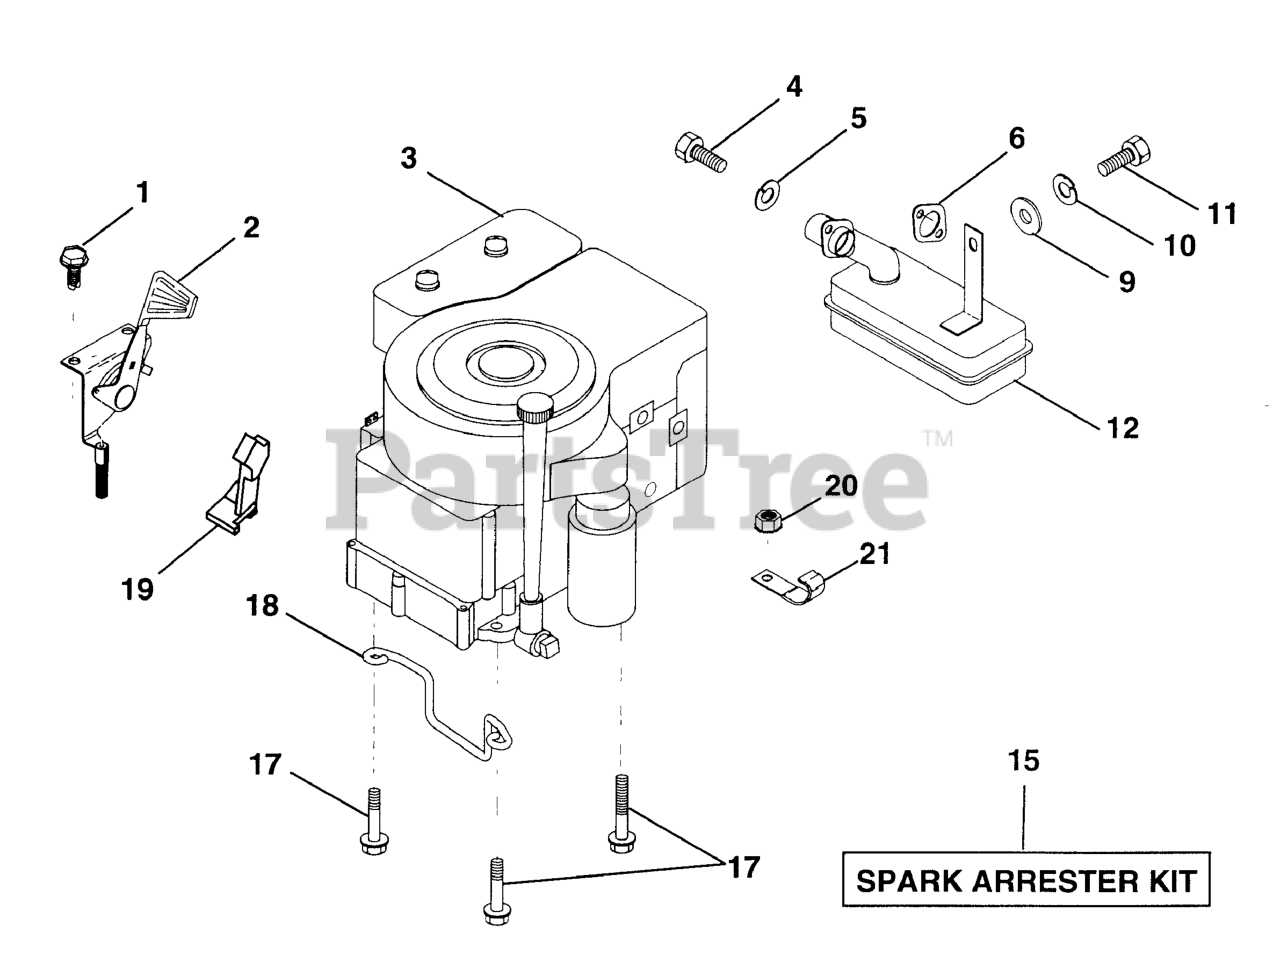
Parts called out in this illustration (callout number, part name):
2	CONTROL.TH/CH.RH.BLK.FLG.EEC
3	Engine, Briggs and Stratton Model No. 282707
4	SCREW
5	WASHER.LOCK.HVY.HLCL.SPR.5/16
6	GASKET ENGINE
9	WASHER
10	LOCKWASHER
11	Bolt, Hex Fin.
12	MUFFLER.SINGLE.B&S.12HP
15	KIT.SPARK ARRESTOR 794945 B&S
17	SCREW LT
18	KEEPER,DR BELT GR
19	STOP THROTTLE
21	CLIP T
